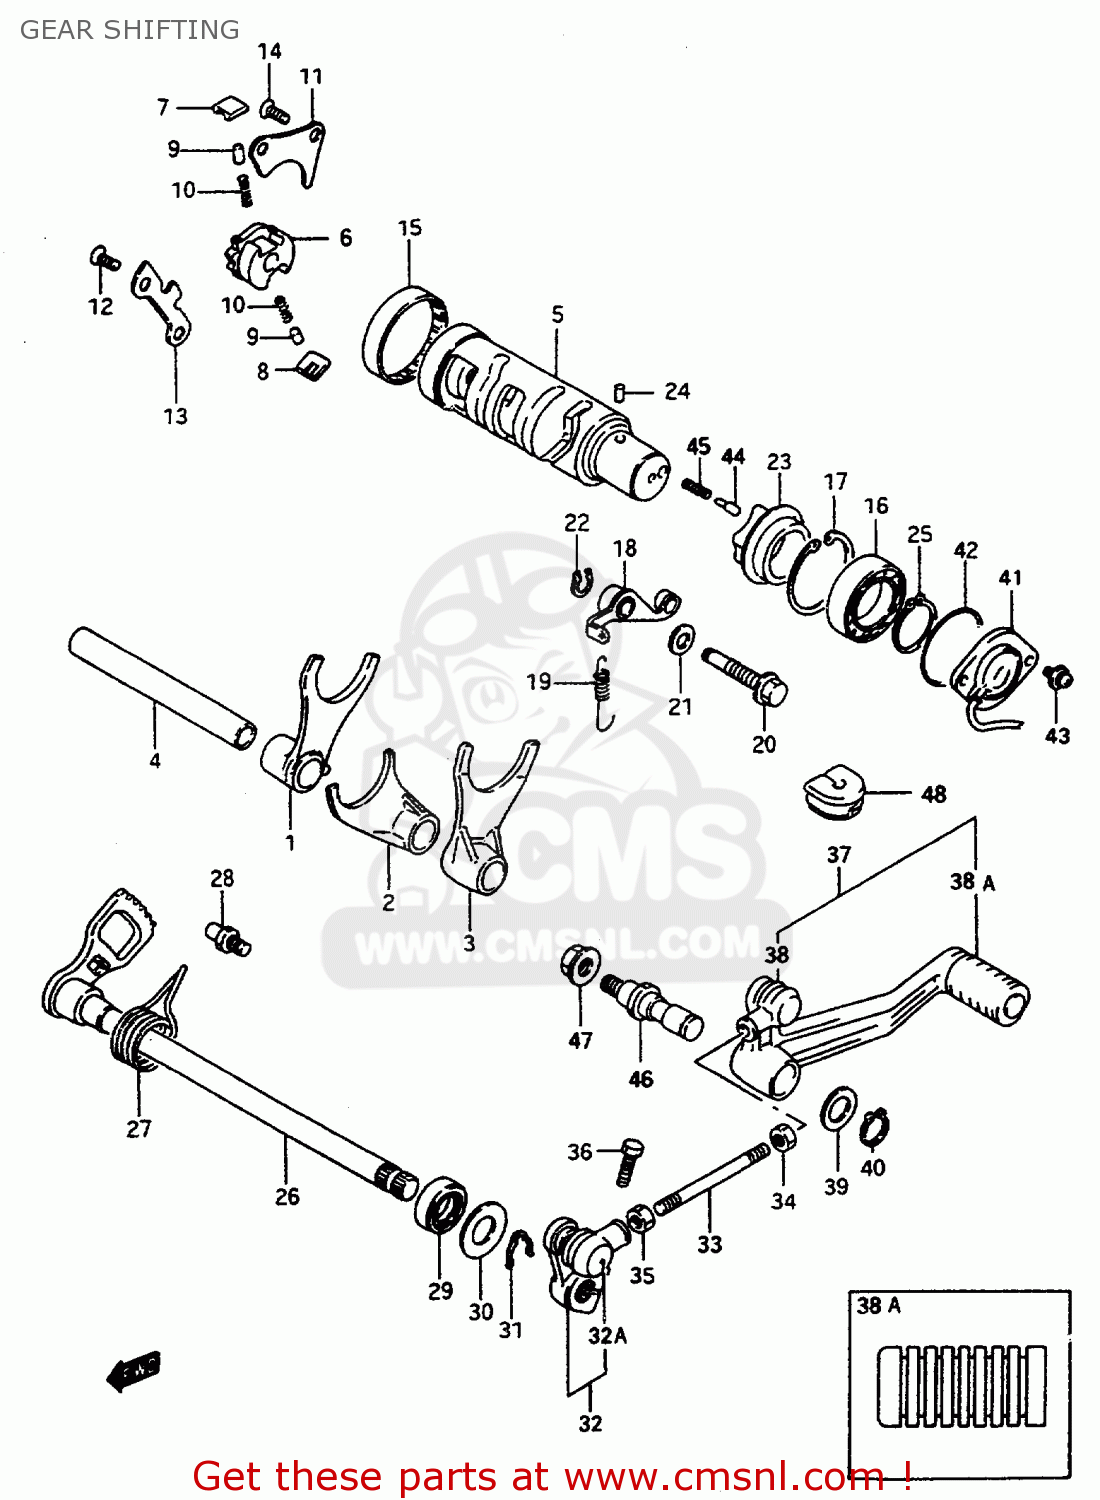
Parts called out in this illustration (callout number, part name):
1	FORK,GEAR SHIFT NO.1
2	FORK,GEAR SHIFT NO.2
3	FORK,GEAR SHIFT NO.3
4	SHAFT,GEAR SHIFT FORK(L:128)
5	CAM,GEAR SHIFT
6	GEAR,GEARSHIFT CAM DRIVE
7	PAWL,GEAR SHIFT NO.1
8	PAWL,GEAR SHIFT NO.2
9	PIN(5X8)
10	SPRING
11	LIFTER,GEAR SHIFT PAWL
12	SCREW
13	GUIDE,GEAR SHIFT CAM
14	SCREW
15	BEARING(43X49X12)
16	BEARING
17	CIRCLIP
18	STOPPER,GEAR SHIFT CAM
19	SPRING
20	SHAFT,GEAR SHIFT CAM STOPPER
21	GASKET(10X14X3.6) (NAS)
22	CIRCLIP
23	PLATE,STOPPER
24	PIN
25	CIRCLIP
26	SHAFT,GEAR SHIFT
27	SPRING
28	STOPPER,GEAR SHIFT CAM
29	OIL SEAL
30	WASHER (12.5X27X1.6)
31	CIRCLIP,12 MM
32	ARM,GEAR SHIFT LINK
32A	COVER,DUST
33	ROD,GEAR SHIFT LINK
34	NUT
35	NUT
36	BOLT
37	LEVER ASSY,GEAR SHIFT
38	COVER,DUST
38A	RUBBER,GEAR SHIFT PEDAL
39	WASHER(12.5X20X1)
40	CIRCLIP,12 MM
41	BASE ASSY,GEAR SHIFT TERMINAL
42	O RING(D:2.4,ID:35.5)
43	SCREW
44	PIN(5X15.5)
45	SPRING
46	SHAFT,GEAR SHIFT LEVER
47	NUT
48	GROMMET,LEADWIRE
